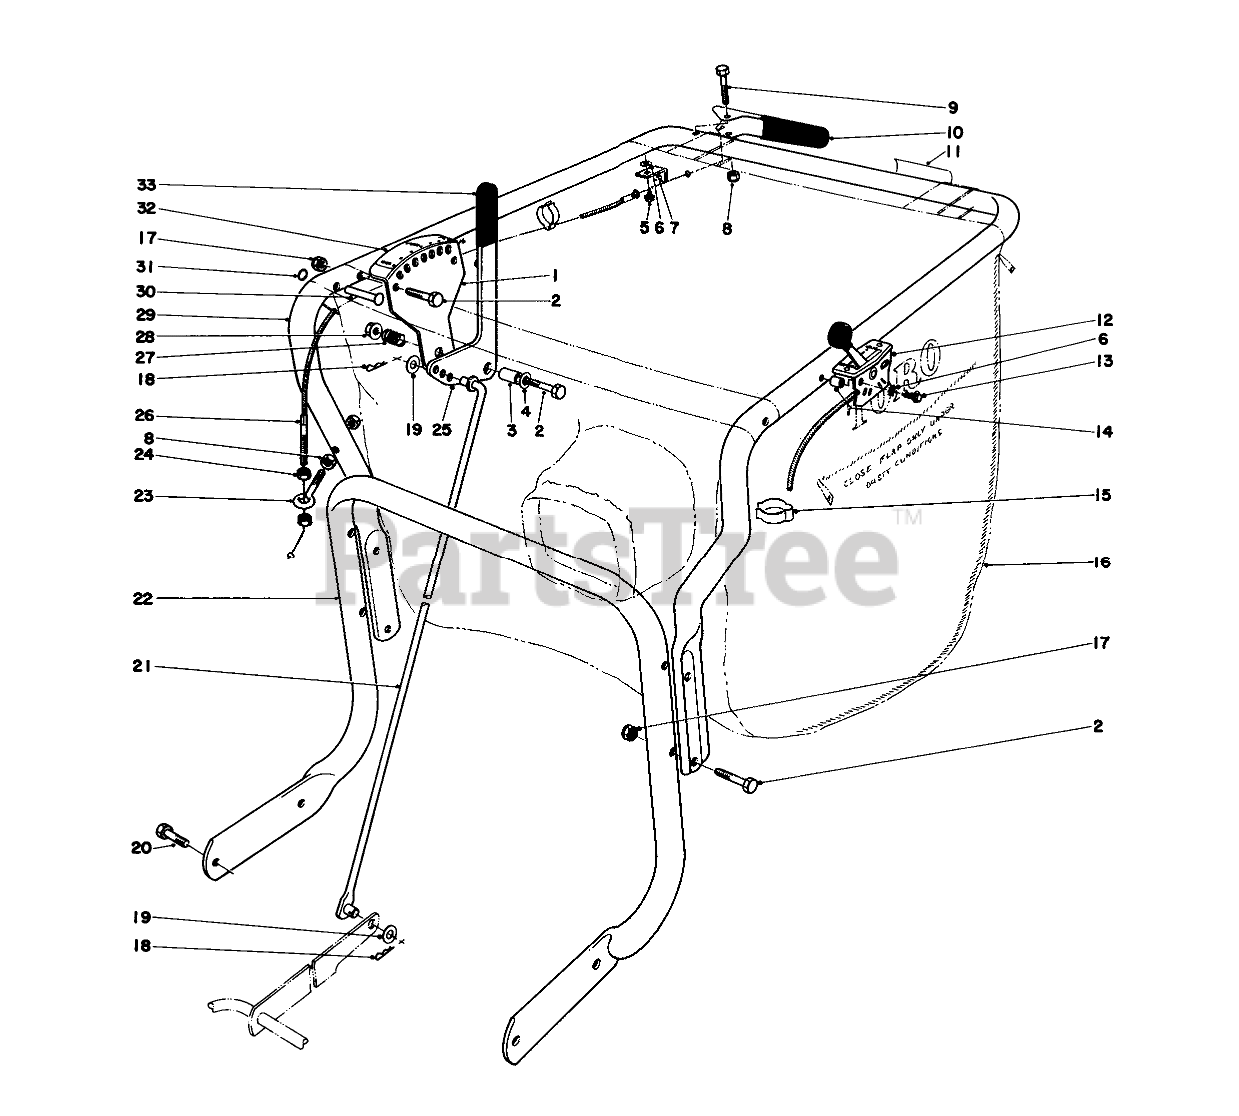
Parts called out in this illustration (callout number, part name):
1	Adjustment Bracket
2	SCREW-HH
3	SPACER
4	WASHER-FLAT
5	SCREW-HWH
6	WASHER-LOCK, EXT
7	RETAINING-CLIP
9	SCREW-HH
10	LEVER W/GRIP
11	TRACTION CONT DECAL
12	THROTTLE CONTROL
13	10-24 X 1 PAN HD SCR
14	SPACER
16	Bag-Vacuum
17	NUT-LOCK, CONE
18	PIN-COTTER
19	WASHER-FLAT
20	Screw
21	Connector Rod
22	HANDLE
23	Eye Bolt
24	NUT-KEPS
25	Handle-Adjustment
26	FWD ASSY CABLE
27	SPRING-COMPRESSION
28	NUT-HF
29	HANDLE-UPPER, VACUUM
30	RIVET
31	RING-GRIP
32	HT ADJ DECAL
33	GRIP-HANDLE
